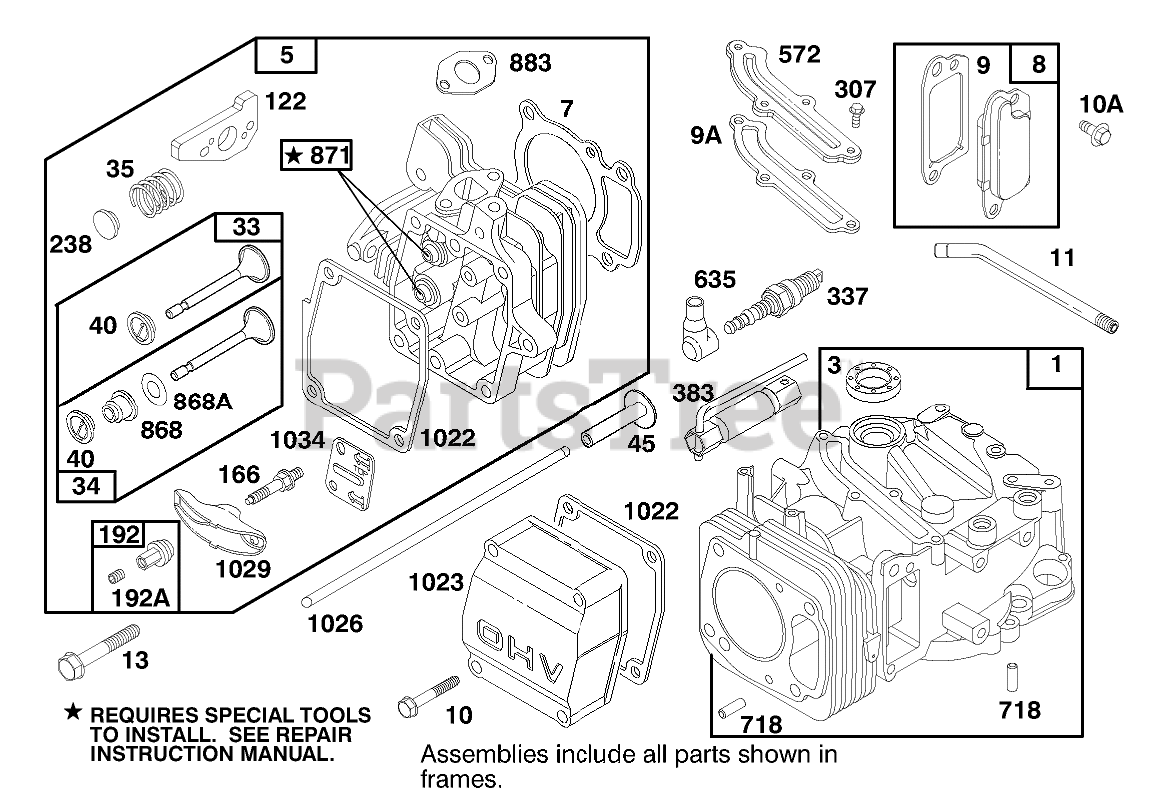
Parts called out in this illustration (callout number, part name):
1	CYLINDER ASSEMBLY
3	SEAL - OIL
5	CYLINDER HEAD
7	CYLINDER HEAD GASKET
8	Breather Assy
9	BREATHER GASKET
9A	GASKET-BREATHER
10	HEX HEAD SCREW
10A	HEX HEAD SCREW
11	TUBE - BREATHER
13	CYLINDER HEAD SCREW
33	EXHAUST VALVE
34	INTAKE VALVE
35	VALVE SPRING
40	SPRING RETAINER
45	VALVE TAPPET
122	ADAPTER ASSEMBLY
166	ROCKER ARM STUD
192	NUT - HEX SPECIAL
192A	SCREW SET
238	VALVE CAP
307	SCREW - SEM
337	PLUG-SPARK
383	WRENCH-SPARK PLUG
572	BAFFLE - CYCLINDER
635	SPARK PLUG ELBOW
718	DOWEL - SLEEVE
868	SealAssy-Valve
868A	Seal-Valve
883	EXHAUST GASKET
1022	ROCKER COVER GASKET
1023	COVER - VALVE
1026	PUSH ROD
1029	ROCKER ARM
1034	PUSH ROD GUIDE
